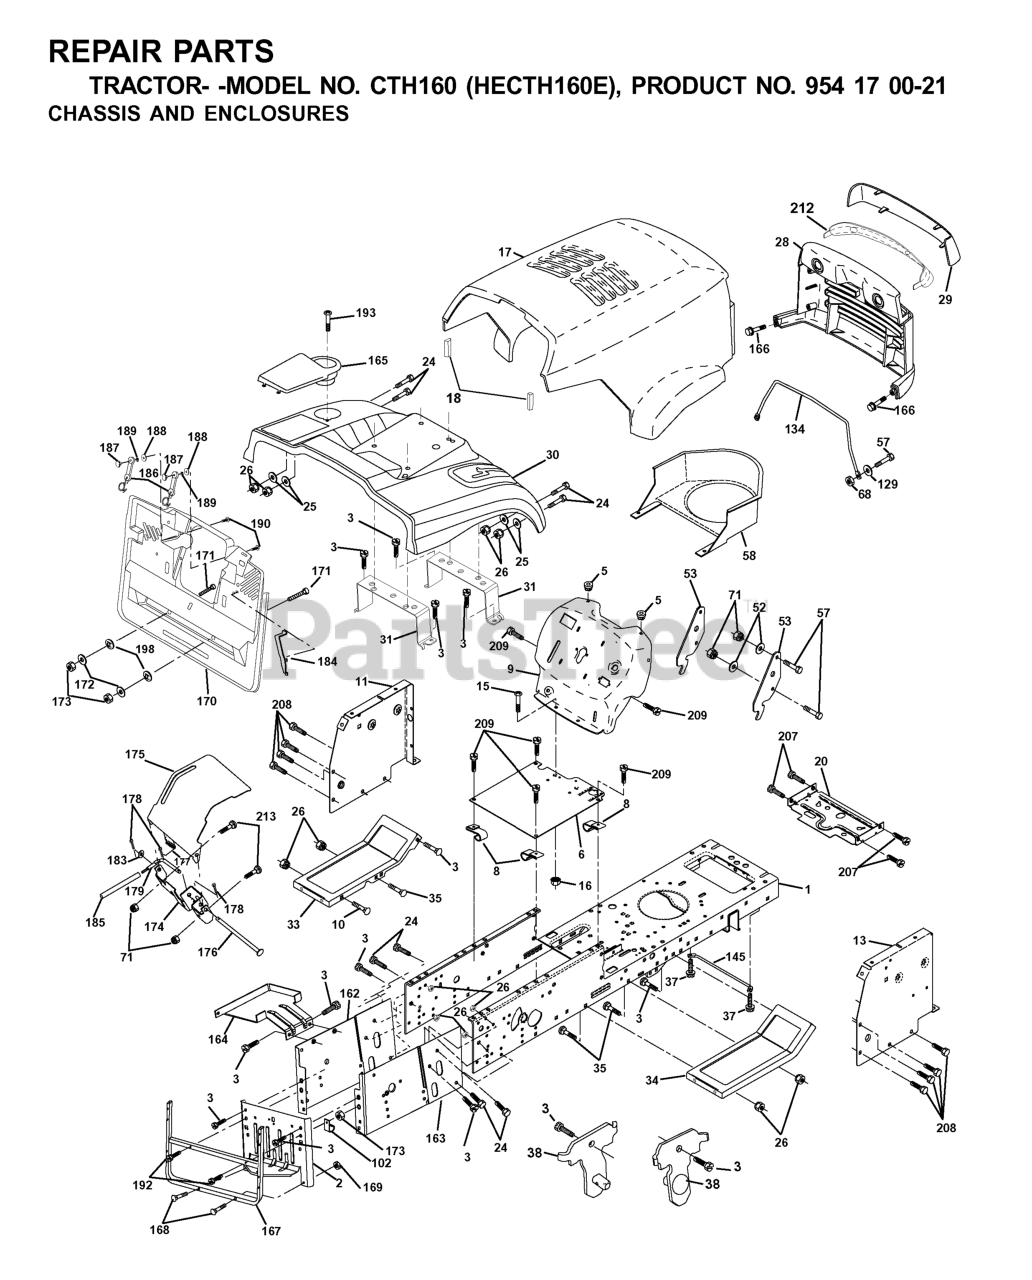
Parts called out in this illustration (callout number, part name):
1	CHASSIS STAMPING
3	SCREW 3/8-16X3/4
5	BUMPER.RUBBER.HOOD
6	SADDLE FLAT
8	CLIP,INSULATOR
10	BOLT D
11	PANEL DASH LH
13	DASH PANEL RH
15	Screw, Machine, Truss Head 5/16-18 UNC x 3/4
16	NUT
17	HOOD
18	BUMPER HOOD T
20	PLATE MTG
25	WASHER
26	NUT
28	GRILL
29	LENS
30	FENDER.CRD.ORANGE
31	BRACKET SUPPORT FENDER
33	FOOT REST LH
34	FOOTREST RH
37	Screw 5/16-18 x 1/2 Hex, Self Tapping 5/16-18 x 1/2
38	BRACKET
53	BRACKET PNT PICK OFF LT/PL
57	BOLT
58	AIR DUCT P/L/LT
68	NUT
71	NUT.CROWNLOCK.1/4
102	CLIP T
134	ROD SUPPORT HOOD LT/PL HUS.
145	ROD PIVOT CHASSIS/HOOD
162	Bracket Exten Chassis Lh CRD
165	COVER BATTERY
166	SCREW
167	SUPPORT.ASM.BACKPLATE
168	BOLT.ROUND.HEAD.SQUARE.NECK
169	NUT T
170	BACKPLATE ASM
171	Bolt Hex 3/8-16 x 2-1/2 Gr. 5
172	WASHER
176	HINGE PIN
177	SPRING COVER LH
178	COTTER PIN
180	BOLT RB
181	LOCKNUT
183	WASHER
184	BRACKET.ACTUATOR.BAGGER.SRD
185	TUBE LEVER
186	LATCH ASSY
187	WELDNUT
189	LOCKWASHER #10
190	SCREW
192	SCREW LT
193	Screw Truss 1/4-20 x 3/4 Tap/R
207	SCREW, 5/16-18 X 1/2
208	SCREW 3/8-16X1/2
209	SCREW, 3/8-16X3/4
212	INSERT LENS REFLECTOR
